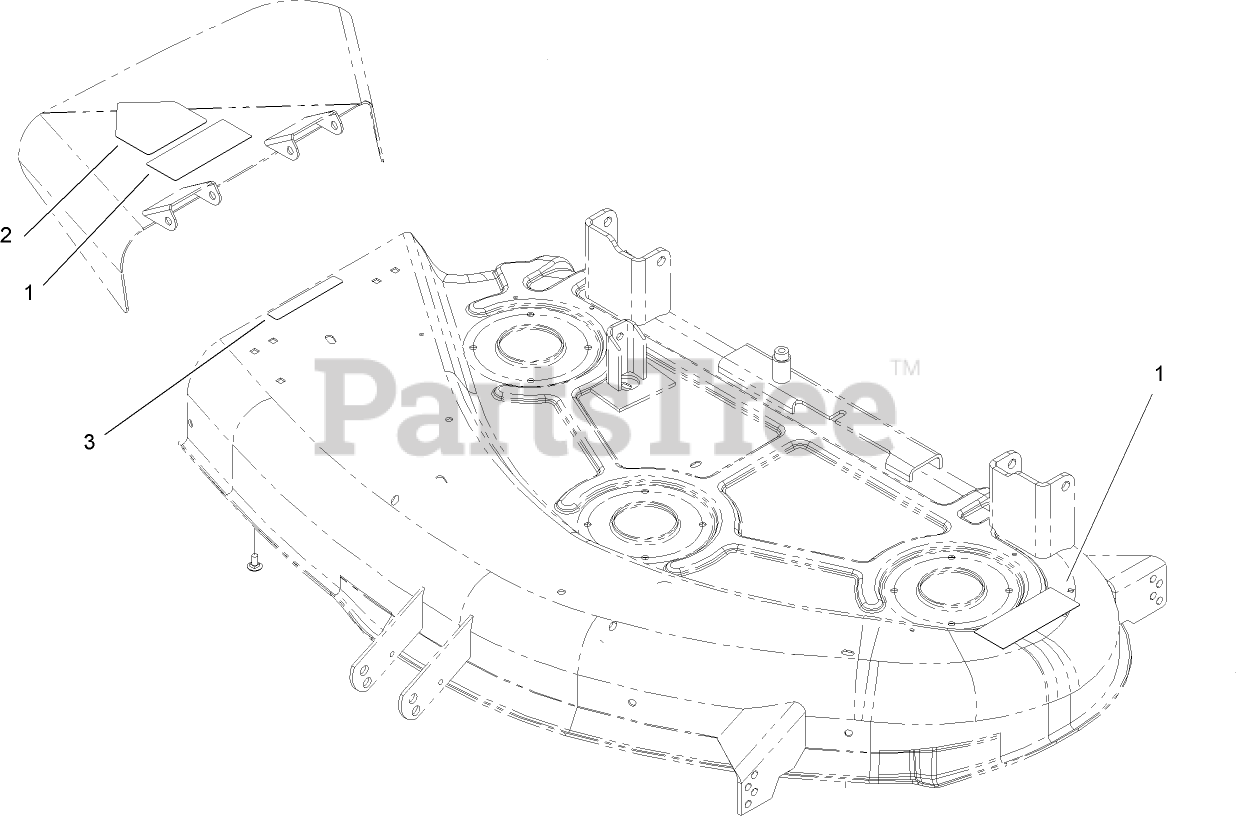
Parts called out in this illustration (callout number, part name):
1	DECAL-DANGER
2	DECAL-DANGER
3	DECAL-DANGER
